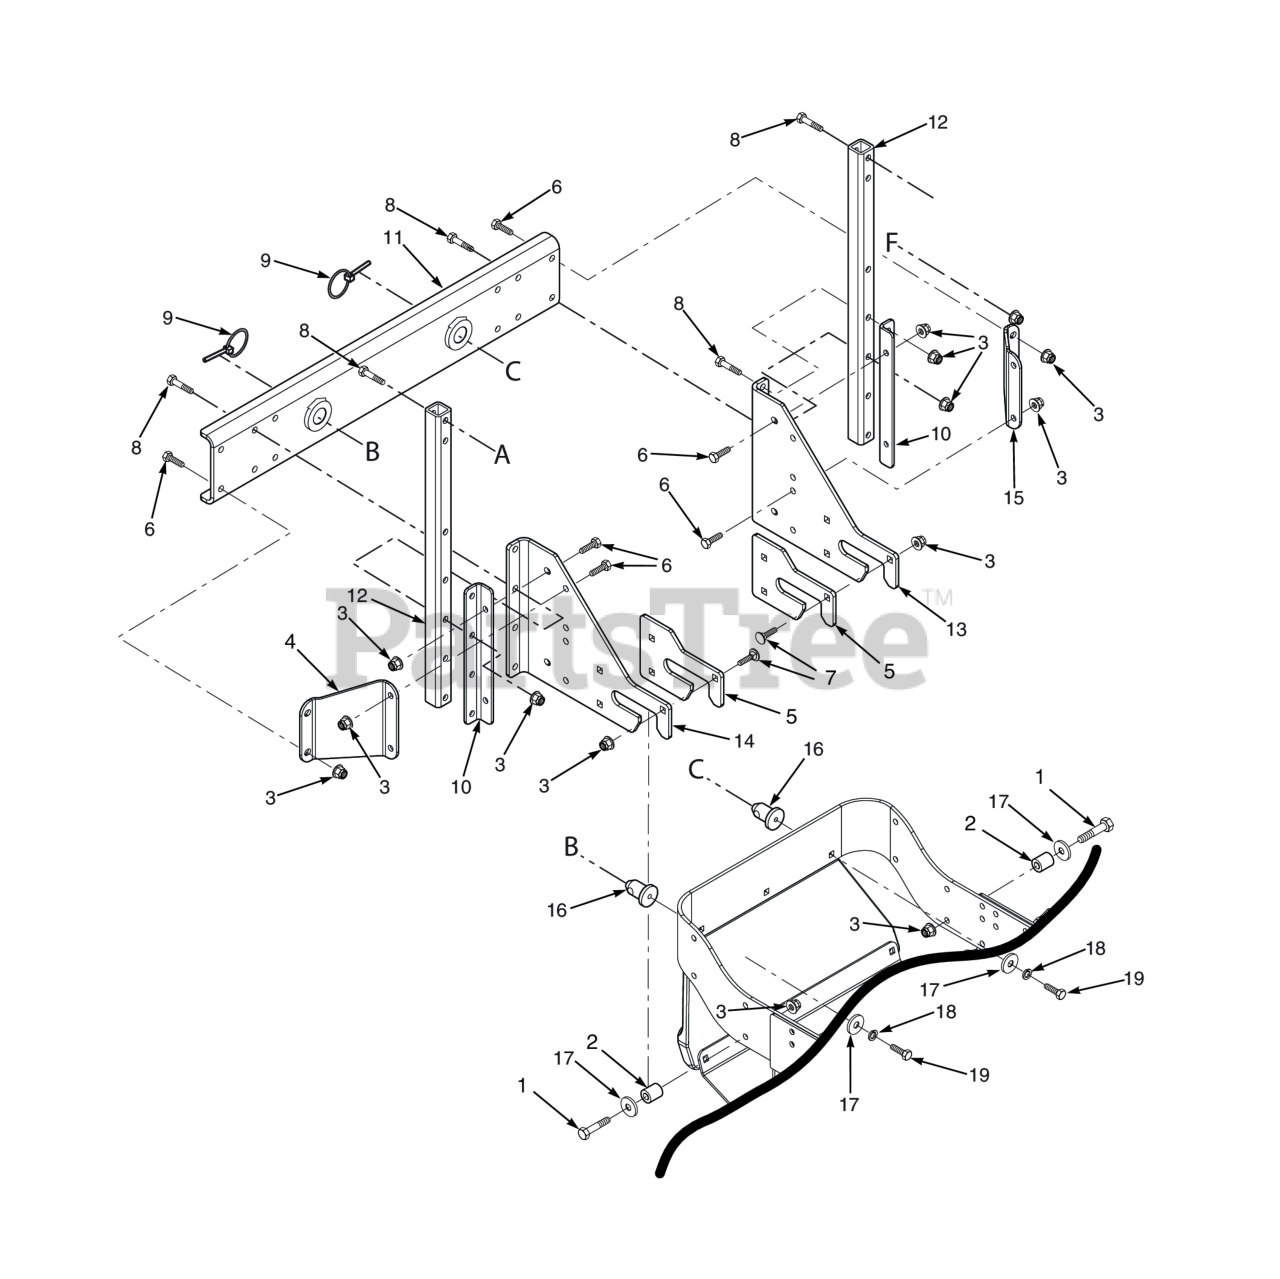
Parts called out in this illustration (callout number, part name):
1	Bolt, Hex Head 3/8-16 x 2-1/4" - 61"
2	Spacer
3	Nut, Flange Elastic Stop Nut, 3/8-16
4	Angle Bracket, GC
5	Wear Plate, GC
6	Bolt, Hex Head 3/8-16 x 1"
7	Carriage Bolt, 3/8-16 x 1-1/4"
8	Bolt, Hex Head 3/8-16 x 2-1/4" - 61"
9	Quick Pin, 5/16" Dia.
10	Mounting Bracket, Tube
11	Mounting Bracket Weldment
12	Tube, Upright
13	Mounting Bracket, GC R.H.
14	Mounting Bracket, GC L.H.
15	Angle Bracket, GC
16	Pin, GC Locator
17	Flatwasher, 3/8-.406 x 1-1-1/2 x 7 Gauge
18	Lockwasher, 3/8" Spring, Kawasaki FX / FT & FT-EFI / B&S 32BV
19	Bolt, Hex Head 3/8-16 x 1-1/4" Grade 8
